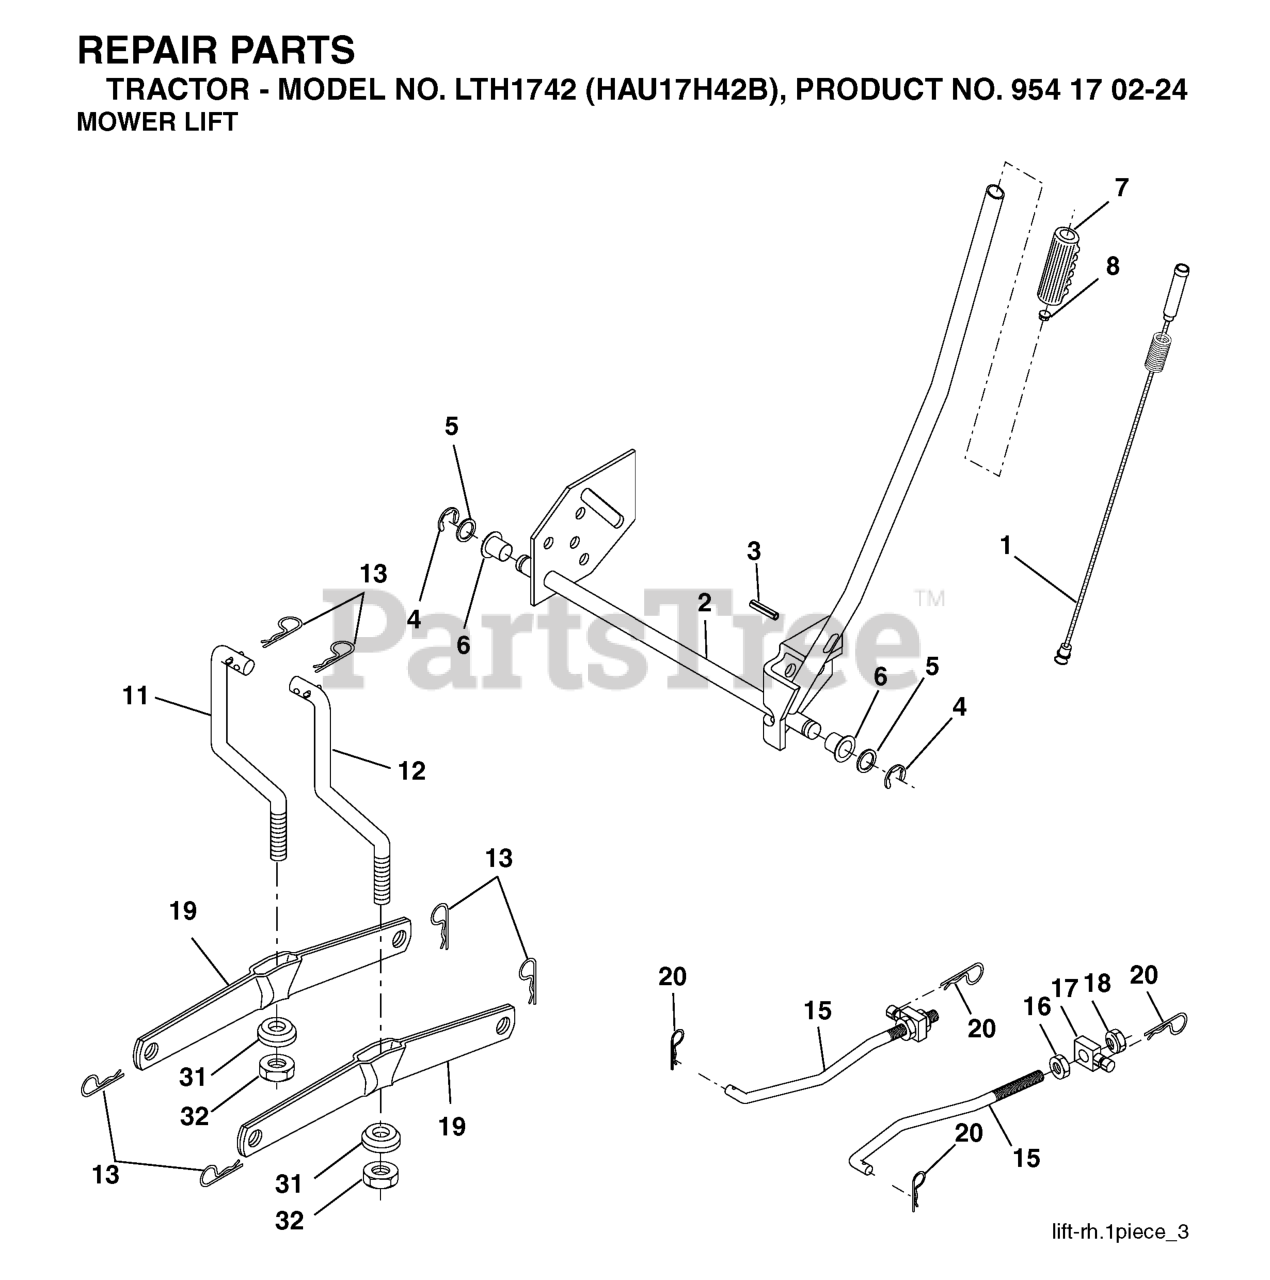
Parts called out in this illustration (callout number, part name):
1	WIRE ASM INNER W/ PLUNGER LT
2	SHAFT ASM R HANDLE
3	PIN GROOVE.
4	RETAINING RING LT
6	BEARING.NYLON
7	GRIP HANDLE
8	PLUNGER BUT KIT
11	LINK LIFT LH
12	LINK LIFT RH
13	RETAINER-SPRNG RB
15	LINK.SUSPENSION.FRONT
16	NUT.HEX.JAM.1/2-13
18	NUT.LK.W/WSH.1/2.
19	ARM.REAR.SUSPENSION
20	SPRING RETAINER
31	BEARING.PIVOT.LIFT
32	NUT CROWNLOCK 3/8-24
